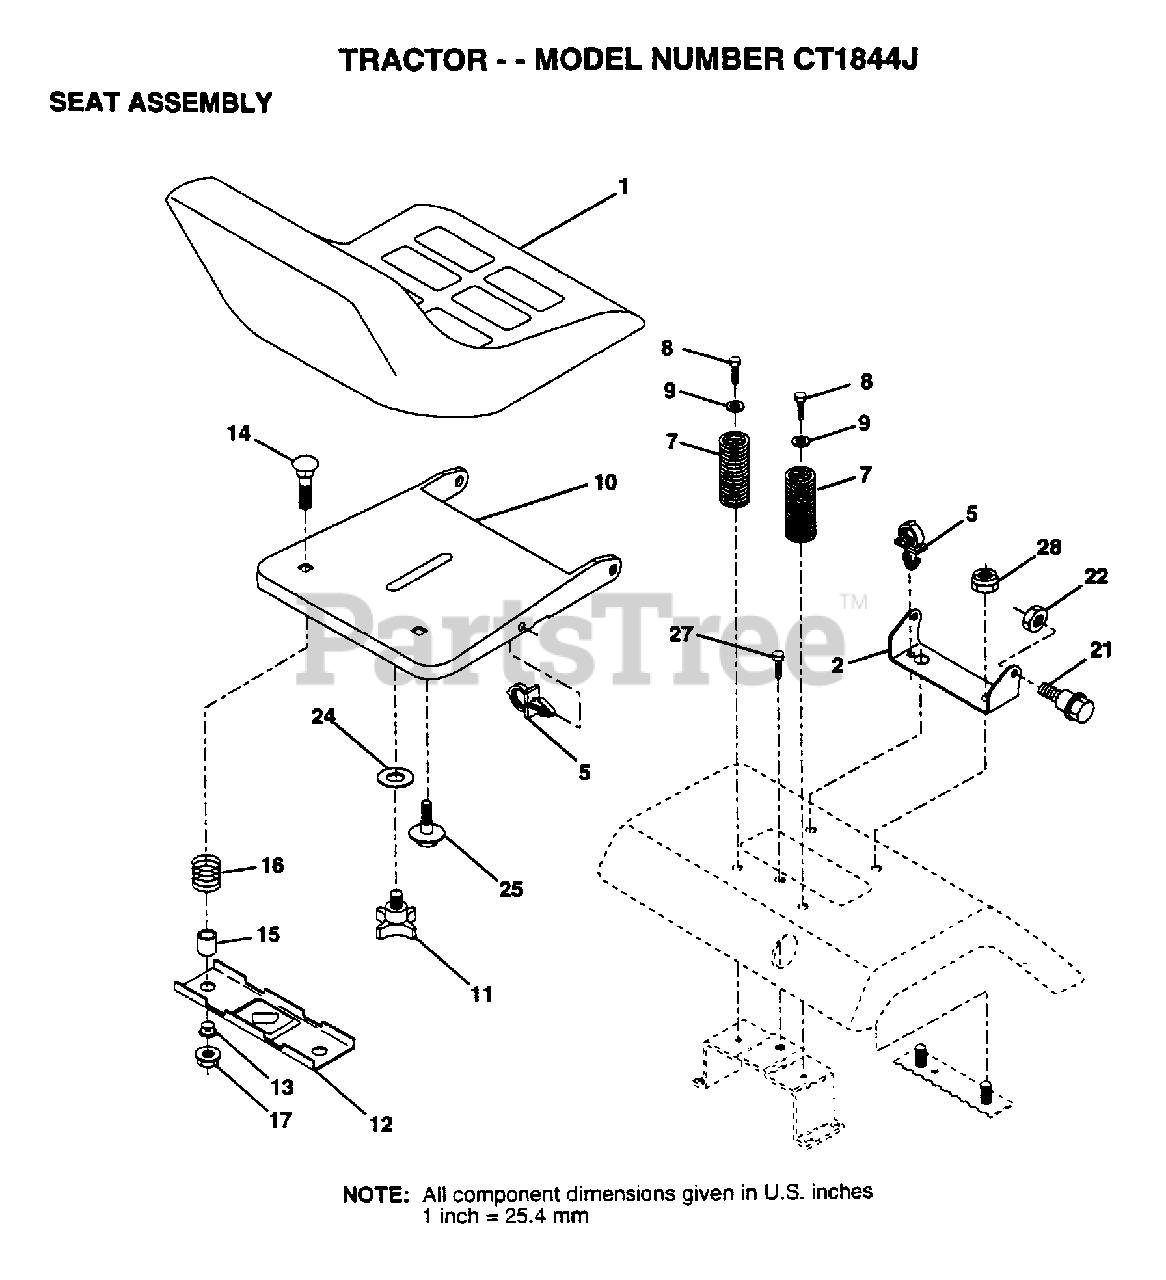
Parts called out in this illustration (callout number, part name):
2	BRACKET PVT SEAT
5	CLIP.PUSH-IN.HING
7	SPRING COMPRESSIO
8	SCREW LT
9	WASHER
11	"KNOB 1/2"" YT"
12	BRKT SWITCH
13	BUSHING
15	SPACER SPLIT
16	SPRING COMPRESSED
21	BOLT.SHLD.5/16-18
24	WASHER
25	"BOLT,SHOULDER"
27	SCREW LT
